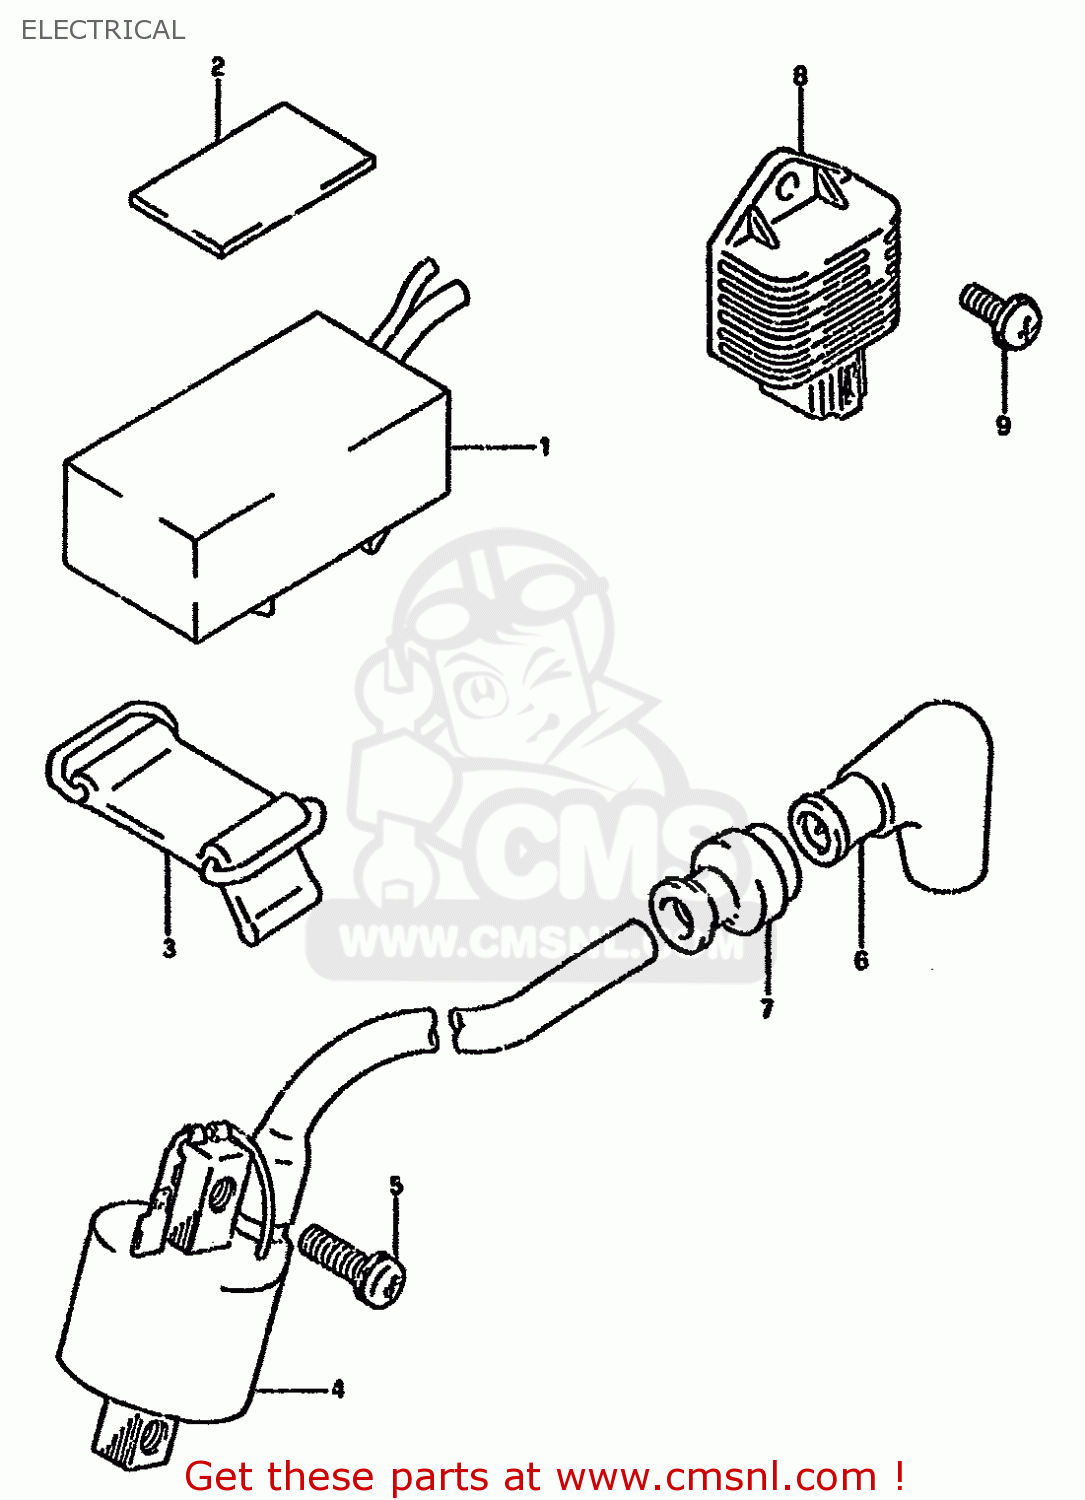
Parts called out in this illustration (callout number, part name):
1	CDI UNIT
2	PROTECTOR(170X95X3.0)
3	BAND(L:65)
4	COIL ASSY,IGNITION
5	SCREW
6	CAP,SPARK PLUG
7	SEAL,HIGH TENSION CORD
8	REGULATOR ASSY
9	SCREW
